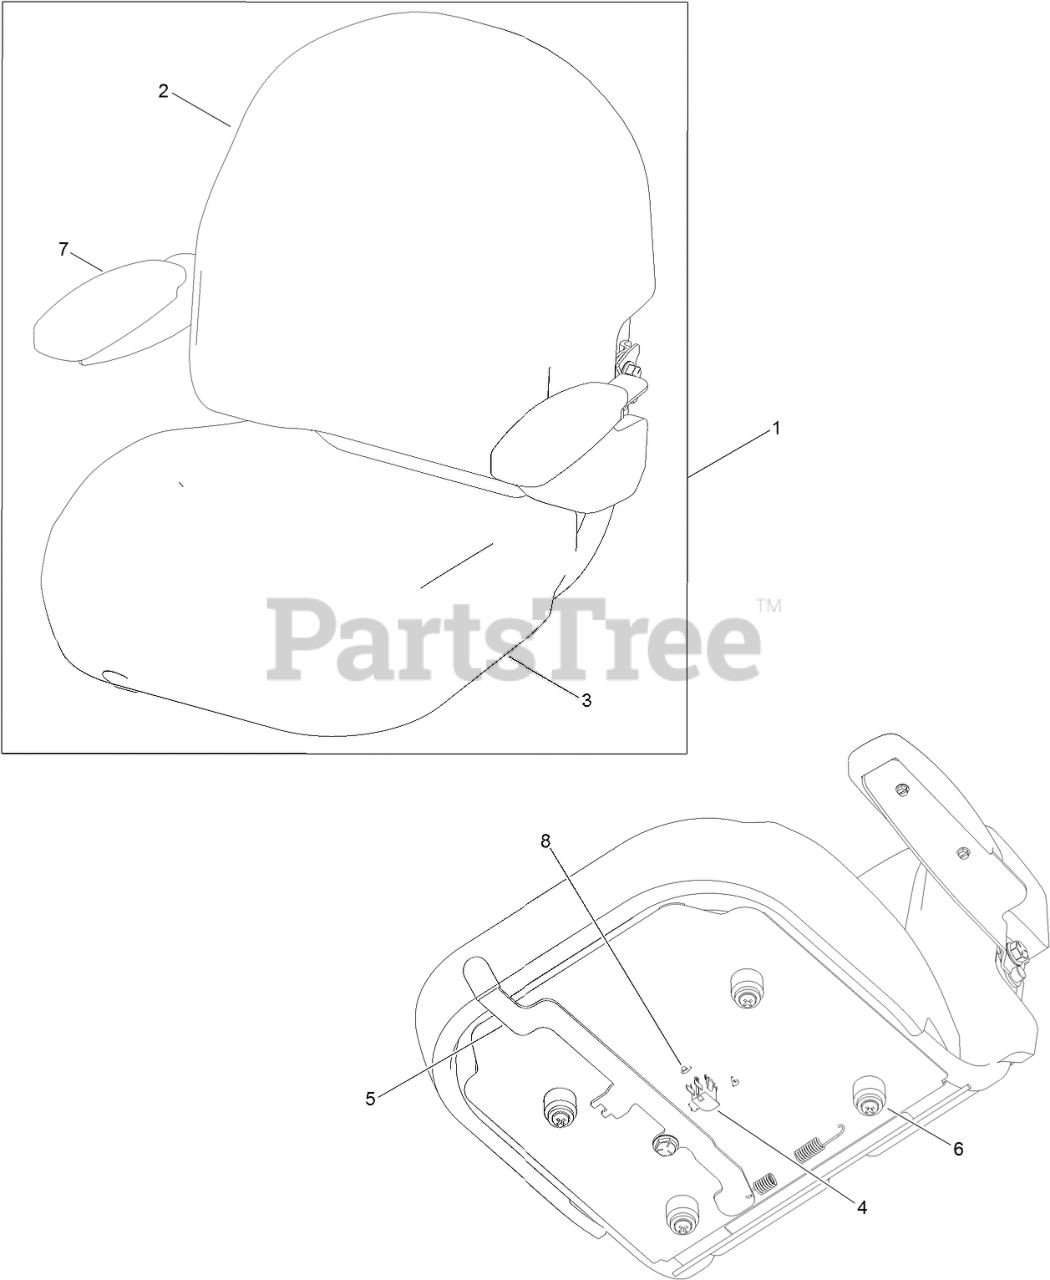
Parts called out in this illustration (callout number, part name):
1	SEAT ASM
2	COVER-SEAT BACK
3	COVER-SEAT BASE
4	SWITCH-BAIL
5	TRACK ASM
6	BUSHING ASM
7	KIT-ARM REST
8	CAP-SWITCH, ACTUATOR
